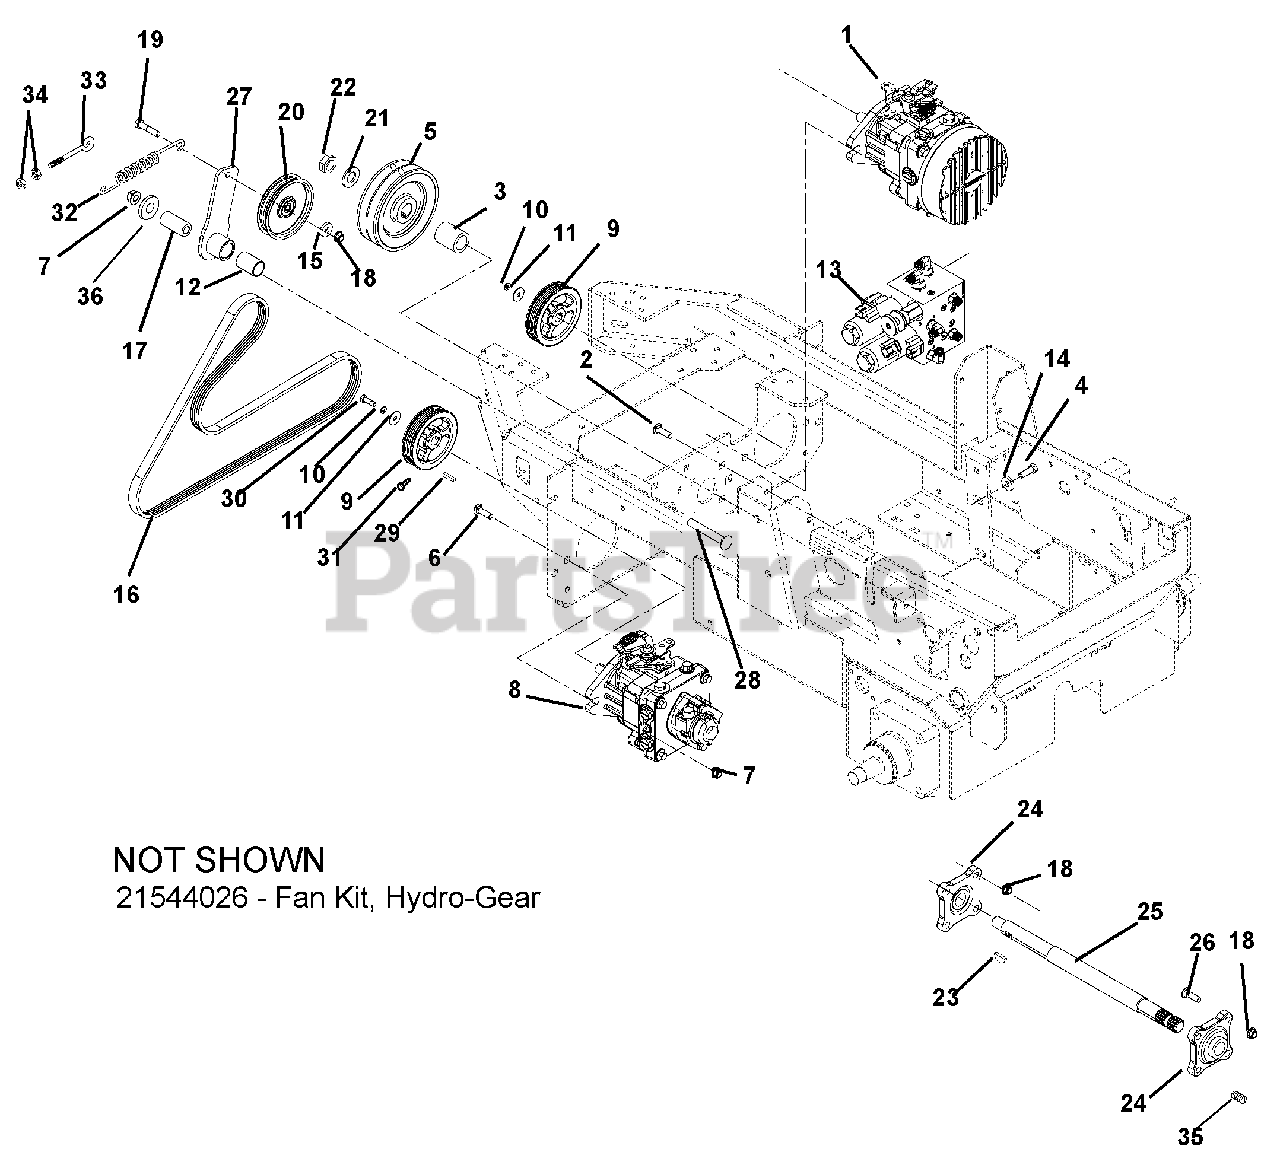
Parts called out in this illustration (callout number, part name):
1	Pump, Hydraulic BDP-21L-Left Hand RAPID XZ
2	Bolt, Round Head Square Neck .38-16 x 1.25 Grade 5
3	Spacer, 1.0ID x 1.5OD x 1.81 Lining
4	Bolt, Hex .31-18X1.00 Grade 5
5	Sheave, Double 1"ID x 6.26"OD
6	Bolt, Round Head Square Neck .50-13 x 1.50 Grade 5
7	Nut, .50-13 Nyloc Flange
8	Pump, Hydraulic BDP-21L Right Hand RAPID XZ
9	Sheave, Poly V .671 x 4.125
10	Washer, Locking .25 x .06
11	Washer, Flat Steel .281 x 1.000 x .063
12	Bearing, 1.00 x 1.125 x 1.936
13	Valve, 2 Spool Mainifold Block
14	Washer, Flat Steel .344 x 1.125 x .135
15	Washer, Flat Steel .406 x 1.00 x .188
16	Belt, Poly-V 69.39 (5 RIBS)
17	Bushing, Spacer .505/.500 x .999/.996 x 2.05/2.03
18	Nut, .38-16 Nyloc Flange
19	Bolt, Hex .38-16 x 2.25 Grade 5
20	Idler, Flat 4.00 x .38
21	Washer, Flat Steel .812 x 1.50 x .135
22	Nut, Jam Center-Lock .75-16
23	Key, Woodruff .25 x .750 x .313 SAE91
24	Bearing, 1" ID 4 Bolt-Trash Seal
25	Shaft, PTO Jack Shaft RAPIDXZ
26	Bolt, Hex .38-16X1.25 Grade 5
27	Assembly, Idler Pivot Arm
28	Bolt, Round Head Square Neck .50-13 x 3.50 Grade 5
29	Key, Square 5 x 5 x 30MM Plain
30	Bolt, Hex M6-1 x 16
31	Screw, Socket Head .25-20 x .50 PH and Oil
32	Spring, Tension .135 x .69 x 5.75 Weldment 150
33	Bolt, Eye .375-16 x 2.50
34	Nut, Hex .38-16
35	Screw, Set .25-28 x .38
36	Washer, Flat Steel .511 x 1.44 x .125
